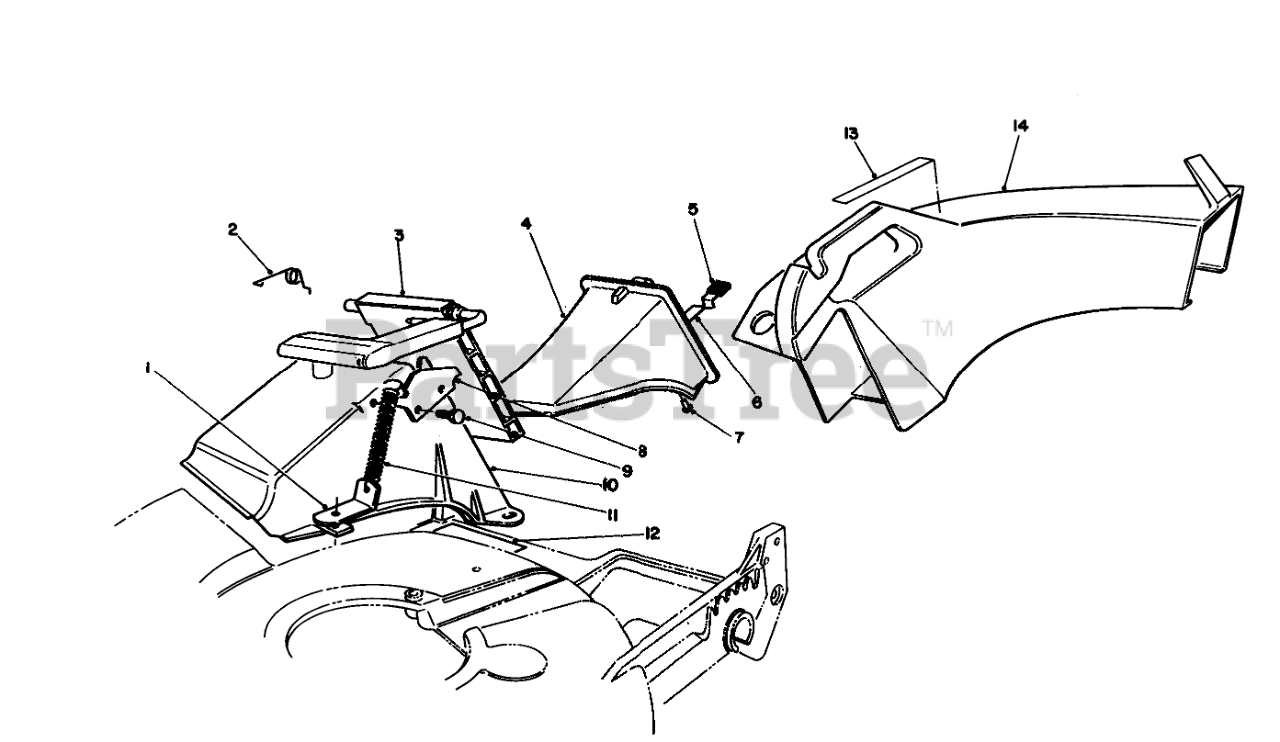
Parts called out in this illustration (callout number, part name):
1	Bracket-Spring
2	RETAINER-DOOR
3	DOOR ASSEMBLY
4	Plug Assembly (Incl. Ref. #5-7)
5	GRIP-LATCH
6	LATCH-PLUG, DISCHARGE
7	RIVET-HEAD, FLAT
8	DOOR LATCH PLATE
9	SCREW-PLASTITE
10	DISCHARGE TUNNEL
11	SPRING-DOOR
12	DECAL - CAUTION
13	DECAL - WARNING
14	CHUTE
